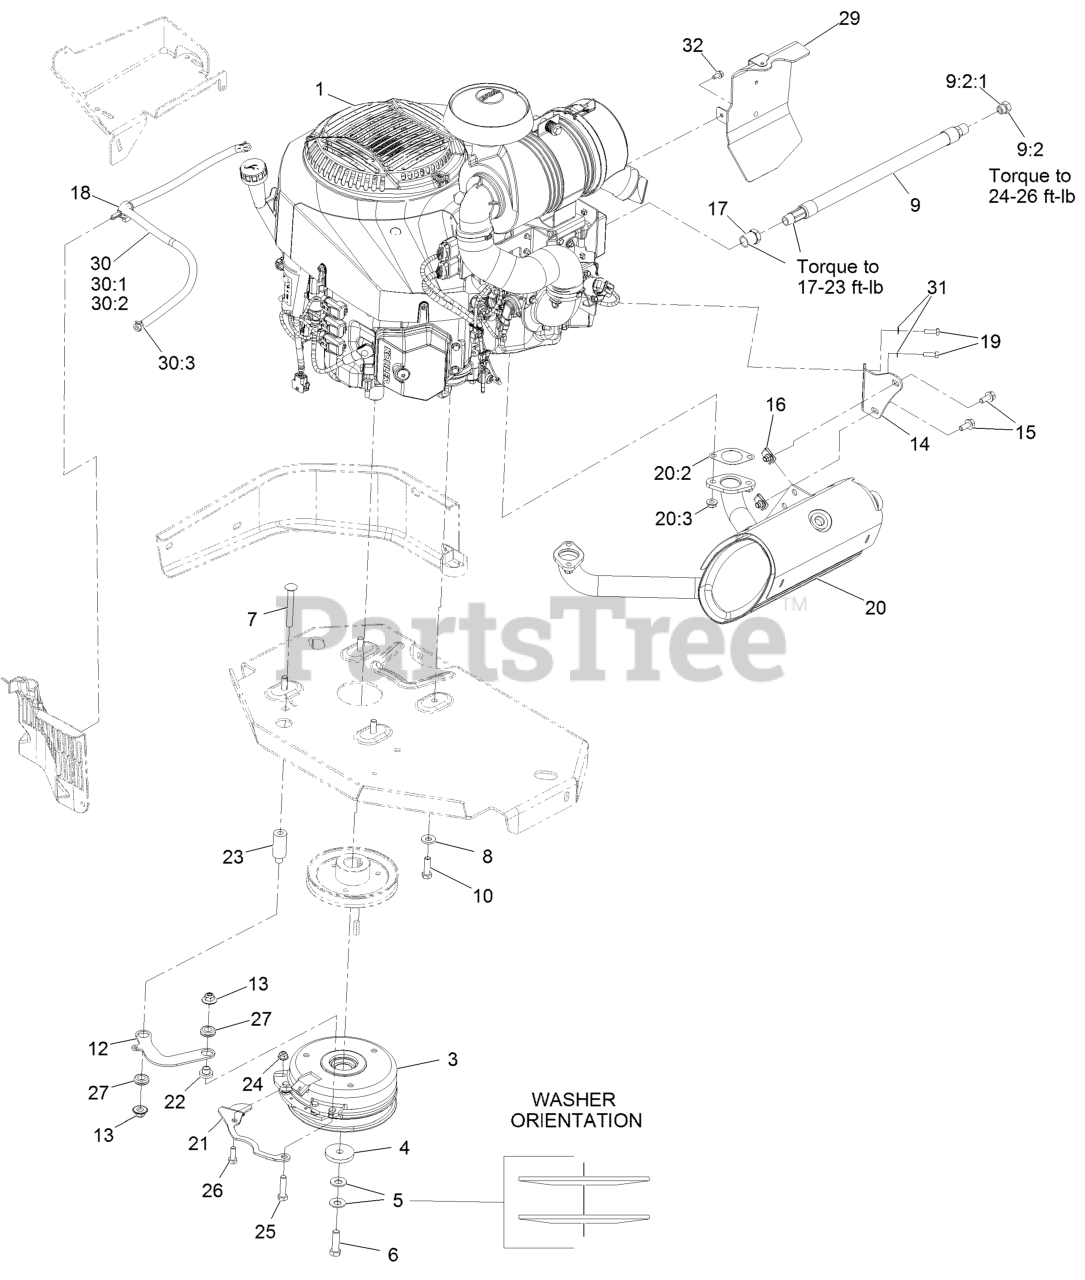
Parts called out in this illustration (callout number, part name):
1	Engine-Koh Ecv940 Efi-Egov
4	WASHER-CLUTCH
5	WASHER-SPRING
6	SCREW-HH 7/16-20 X 1 1/2 W/LOCTITE
7	SCREW-CARR
8	WASHER-BELLEVILLE
9	OIL DRAIN HOSE ASM
9:2	PLUG-HH
9:2:1	O-RING
10	SCREW-HH
12	LINK-ANCHOR, CLUTCH
13	Nut-Nyloc 3/8-16 Flg
14	BRACKET-MUFFLER
15	SCREW-HHF
17	BUSHING
18	CLAMP-HOSE
19	SCREW-HH M6-1 X 20Mm W/Patch
20	MUFFLER-940-980 KOH EFI
20	MUFFLER KIT
20:2	GASKET-EXHAUST
20:3	NUT-FLANGE, LOCK
21	BELT-GUIDE
24	NUT-HF, NI
25	SCREW-HH
26	SCREW-HH
27	GROMMET-RUBBER
29	REAR BAFFLE ASM
30	FUEL LINE ASM
30:1	HOSE-FUEL
30:2	SLEEVE-THERMAL
30:3	CLAMP-HOSE
31	WASHER-SPRING
32	SCREW-HWH
